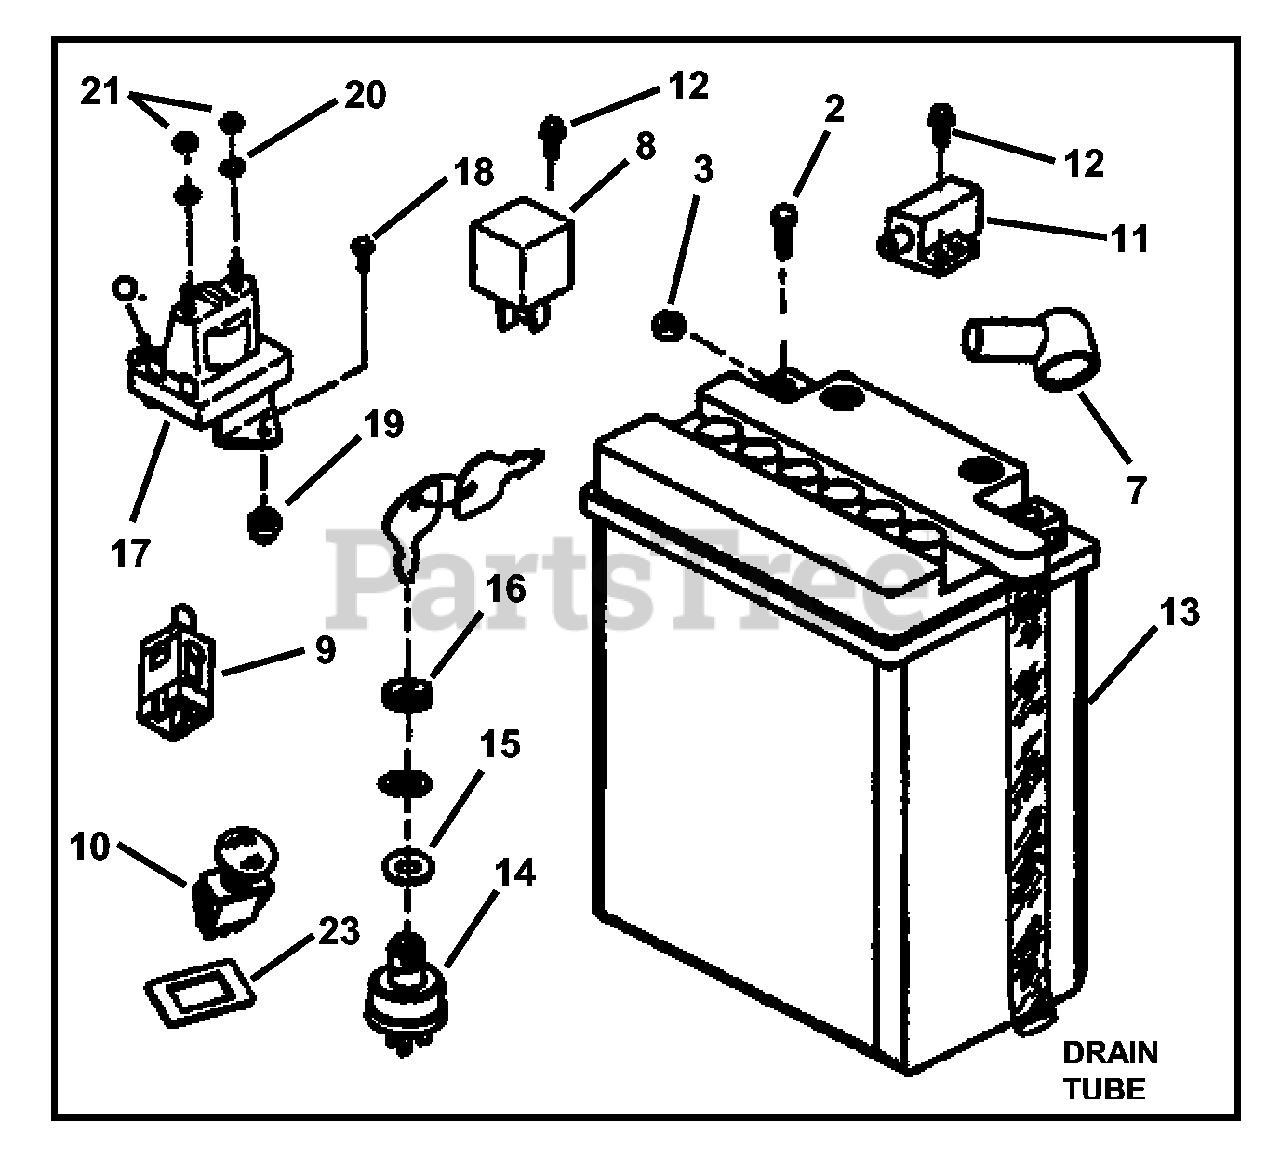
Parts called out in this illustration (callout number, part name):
2	SCREW, #10-24 x 1/2" Hex Head Cap
3	NUT, #10-24 Hex Twin "Whiz" Lock
7	COVER, Battery Cable
8	RELAY, Operator Presence Control
9	SWITCH, Seat (NC/NO)
10	SWITCH, PTO Electric Clutch
11	SWITCH, Park Break (NC/NO)
12	SCREW, #10-24 x 1/2" Hex Washer Self-Tap (Torx)
13	BATTERY, 12 Volt, 14 Amp, 190 Cold Cranking Amp
14	SWITCH, Ignition (After-fire Solenoid)
16	BEZEL
17	SOLENOID, 12 Volt (was 18604)
18	SCREW, 1/4-20 x 1/2" Hex Head Cap, Grade 5
19	NUT, 1/4-20 Hex Flange Lock, Grade 5
20	WASHER, 1/4 Internal Tooth Lock
21	NUT, 1/4-20 Hex Jam
23	SPACER, PTO Switch
